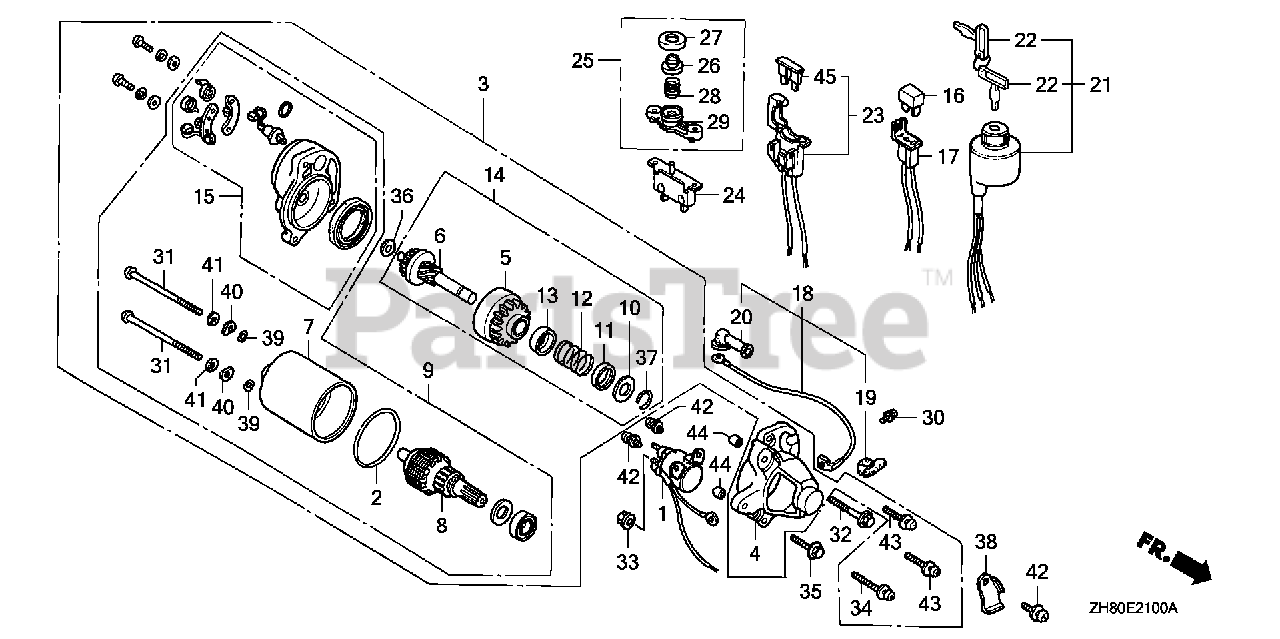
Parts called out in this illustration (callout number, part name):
1	SWITCH, STARTING MAGNET
2	O-RING
3	STARTER MOTOR UNIT (SM-11203) (162MM)
4	COVER, GEAR
5	PINION ASSY.
6	SHAFT UNIT, GEAR
7	YOKE ASSY.
8	ROTOR ASSY.
9	MOTOR ONLY
10	PIECE A, STOPPER
11	PIECE B, STOPPER
12	SPRING, RETURN
13	COVER, SPRING
14	GEAR ASSY.
15	BRACKET, FR.
18	WIRE, MAGNETIC SWITCH
19	COVER, MAGNETIC SWITCH
20	COVER, STARTER MOTOR TERMINAL
30	SCREW-WASHER (5X8)
31	BOLT, SETTING
32	BOLT, FLANGE (6X32) (CT200)
33	NUT-WASHER (6MM)
34	SCREW-WASHER (5X30)
35	BOLT, FLANGE (6X25) (CT200)
36	WASHER, PINION
37	CIRCLIP (10.2MM)
38	HOLDER, HARNESS
39	O-RING
40	WASHER, SPECIAL
41	WASHER, SPRING
42	SCREW-WASHER (5X14)
43	SCREW-WASHER (5X20)
44	PIN, DOWEL (8X10)
